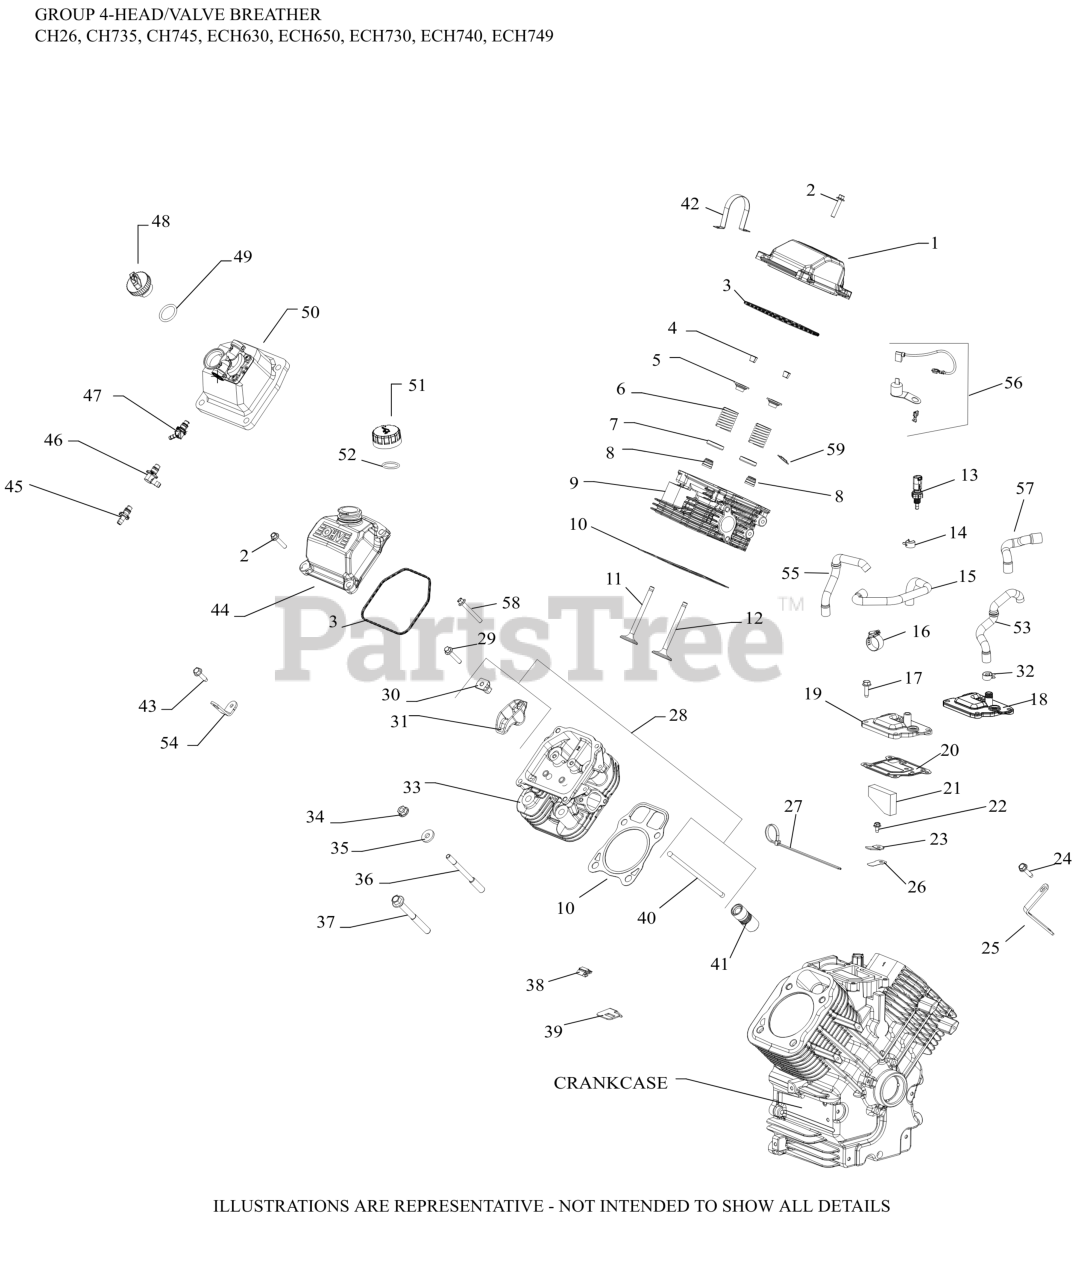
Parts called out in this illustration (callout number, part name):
1	KIT, VALVE COVER-PLAIN (PLASTIC)
2	SCREW, FLG M6X1.0X30
3	O-RING (YELLOW), VALVE CO
4	KIT, RETAINER
5	CAP, VALVE SPRING
6	SPRING, VALVE
7	RETAINER, SPRING
8	SEAL, VALVE BAND
9	KIT, CYLINDER HEAD #1-(#24318218S)
10	KIT, GASKET CYLINDER HEAD
11	VALVE, EXHAUST
11	VALVE, EXHAUST (.25)
12	VALVE, INTAKE (STD)
12	VALVE, INTAKE (.25)
13	SENSOR, TEMPERATURE
15	HOSE, BREATHER (EFI H/S, HDAC)
17	SCREW, THREAD FORMING
19	COVER, BREATHER
20	GASKET, BREATHER
21	FILTER, BREATHER
22	SCREW, FLG THD FRM M5X.8X10
23	RETAINER, REED
25	STRAP, LIFT
26	REED, BREATHER-(#2440206S)
26	REED, BREATHER
28	KIT, VALVE TRAIN
29	SCREW, FLG (BLACK) M6X1.0X34
30	PIVOT, ROCKER ARM
31	ARM, ROCKER
32	SPRING CLAMP, HOSE
33	KIT, CYLINDER HEAD #2-(#24318219S)
34	NUT, FLG M8X1.25
35	WASHER, FLAT 8.6 MM
36	STUD, M8X1.25
38	CLIP, O2 SENSOR
39	BRACKET, OXYGEN SENSOR
40	ROD, PUSH
41	LIFTER, VALVE HYDRAULIC-USE 25 351 11-S
43	SCREW, THREAD FORMING
45	KIT, STRAIGHT FITTING
46	KIT, 90 DEG. FITTING
48	CAP ASSY, OIL FILL (YELLOW)
50	KIT,VALVE COVER-FUEL PUMP
54	STRAP, LIFTING
59	RETAINER, VALVE GUIDE (KM)
